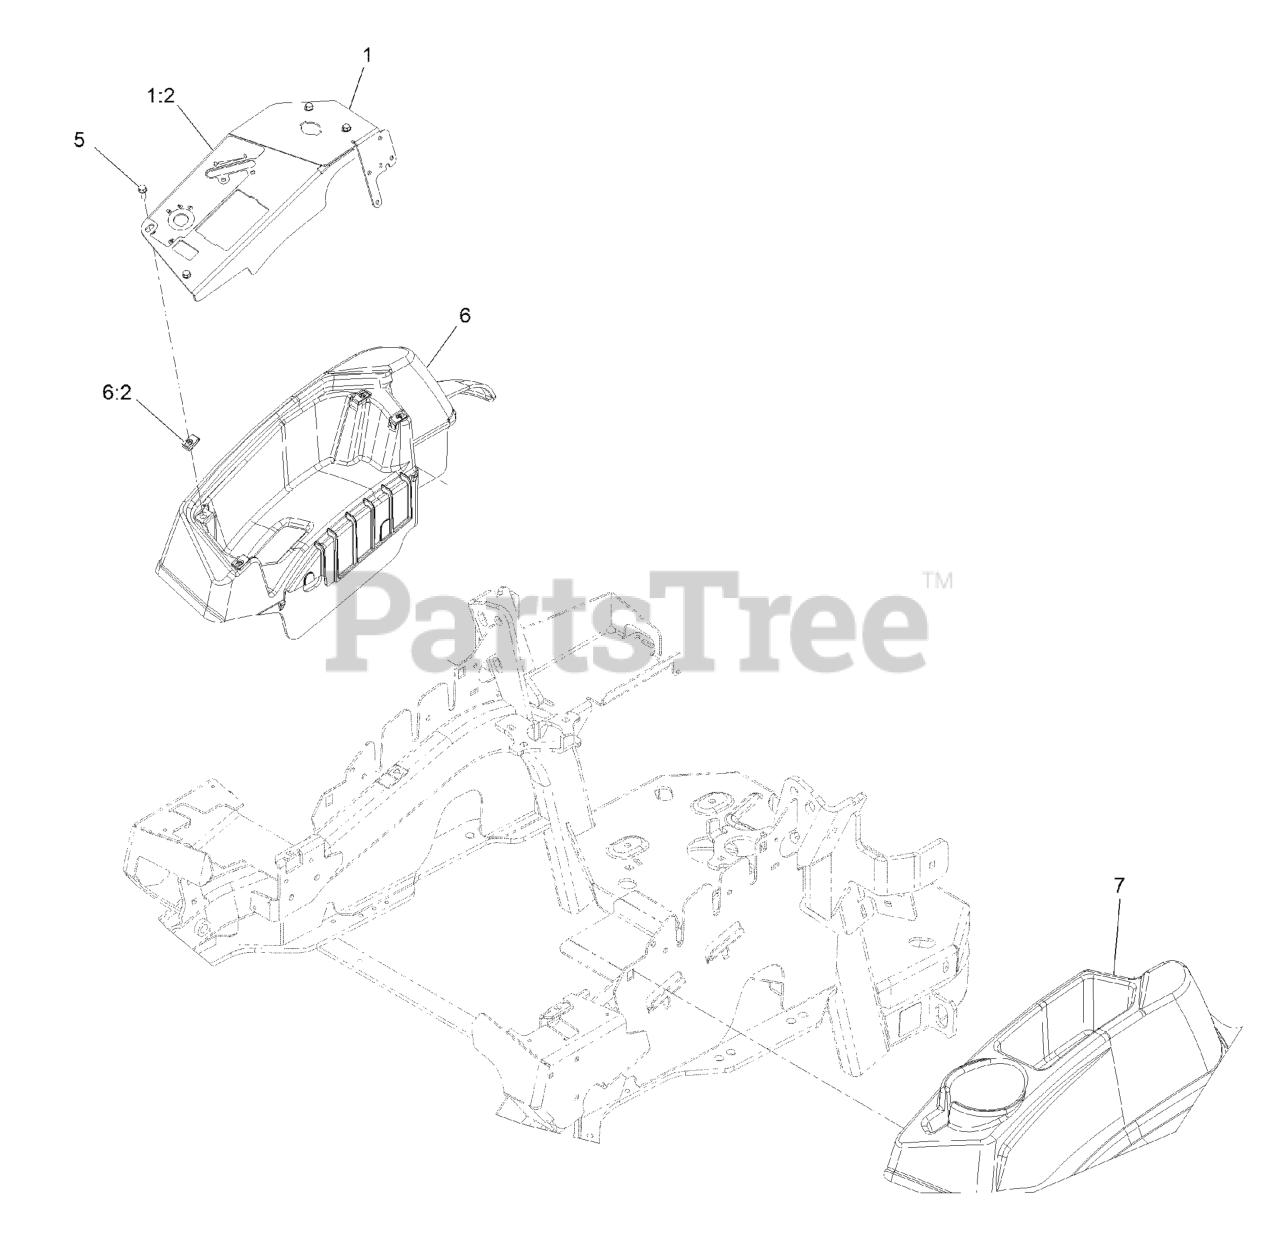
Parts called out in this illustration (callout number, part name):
1	ASM,CONTROL PANEL W/DECAL
1:2	DECAL-CONTROL PANEL EFI
1:3	DECAL-FUSES
2	ASM,THROTTLE CABLE
3	BOLT-CARR
4	NUT-LOCK, NI
5	SCREW-HWH
6	CONSOLE,RH AS ASM
7	CONSOLE, LH AS
8	PLUG-PLASTIC
9	CLAMP-HOSE
